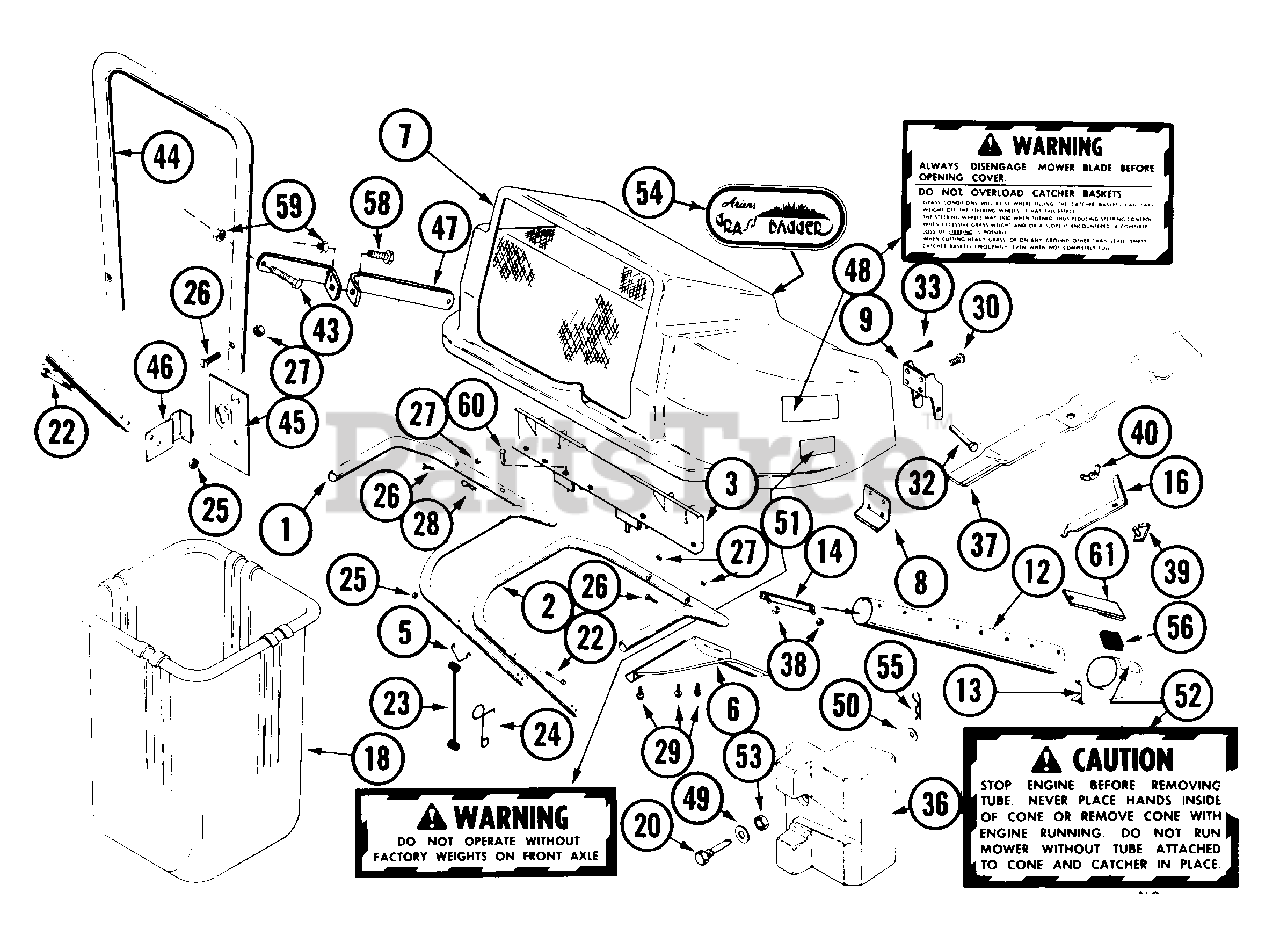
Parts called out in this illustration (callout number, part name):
1	TUBE L.H. SUPPORT
2	TUBE R.H. SUPPORT
6	SUPPORT TUBE
7	GRASS CATCHER COVER ASSEMBLY
8	RETAINER
12	TUBE BLANK
13	CONE ASSEMBLY
16	STRAP CONE
20	STUD-WEIGHT
22	BLT-HEX .25-20X2.25 GR2
23	BATTERY STRAP
24	HOOK
25	NUT-LK-CTR .250-20 PL
26	SCR-MCH .31-18X1.50 CROVCNTRS
27	NUT-LK-NYL.312-18 PL
28	PIN-HAIR INT .08X.38X1.42 YWZC
29	BLT-SERHFWH .25-20X.50 PL
30	BLT-SCRHFWH .25-20X.62 PL
32	CLEVIS PIN
33	PIN-COTR .06X.50
37	MOWER BLADE
38	NUT-LK-FLG .250-20 PL
39	CLIP CONE
40	NUT-WING W/INSERT .312 - 18
43	BLT-HEX .31-18X1.50 PL GR2
44	BAR SUPPORT
45	BRACKET ADAPTER
46	BRACKET MOUNTING
47	BRACKET - ADJUSTMENT
48	WARNING DECAL
49	WSHR-FL-STL .438X1.0X.083 PL
50	WSHR-FL-STL .511X1.441X.125 PL
51	WARNING DECAL
52	CAUTION DECAL
53	NUT-LK-CTR .50-13
54	DECAL-GRASS BAGGER
55	PIN-HAIR INT .09X.188 PL
56	HOOK FASTENER
57	RVT-TBLR .187X.281 OV ST PL
58	BLT-HEX .31-18X2.75 PL GR2
59	NUT-LK .312-18 GR A PL
60	CLEVIS PIN
61	ATTACHING STRAP
